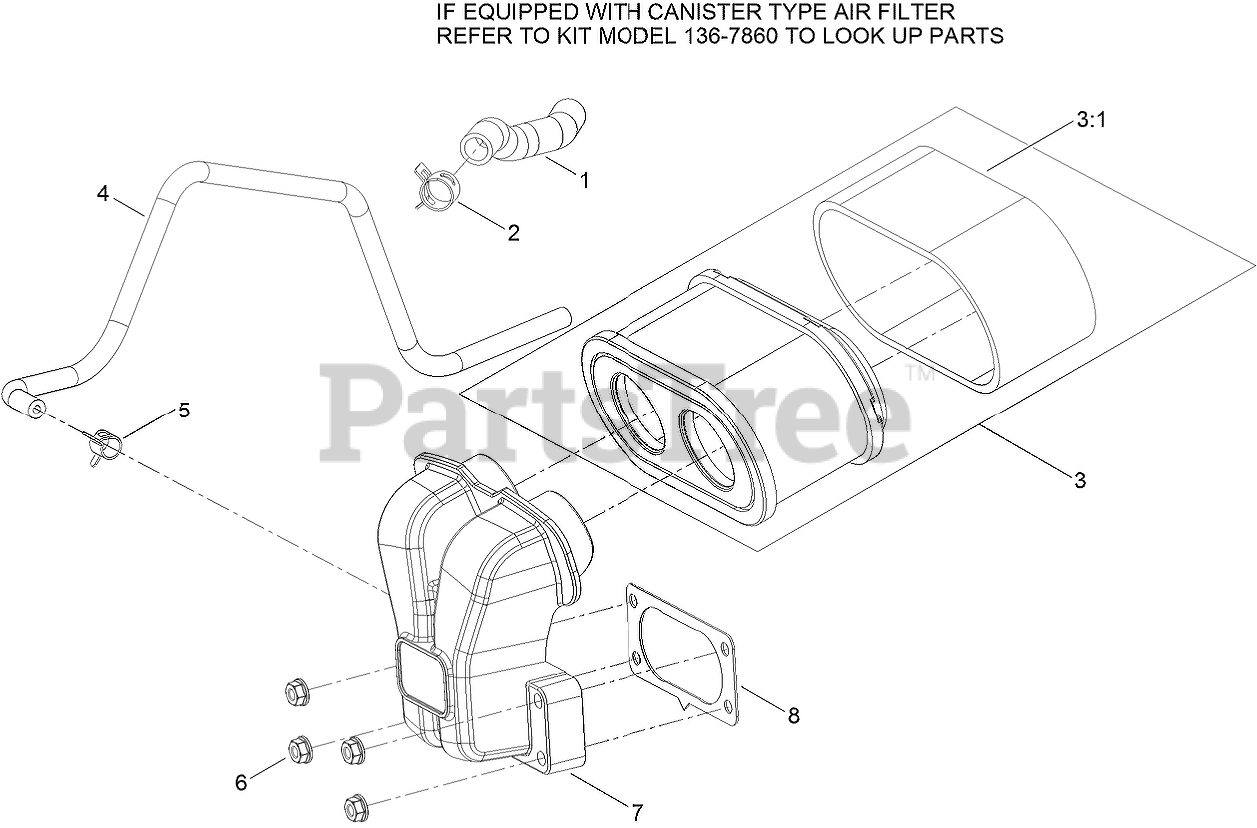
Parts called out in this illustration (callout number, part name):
1	TUBE-BREATHER
2	CLAMP-HOSE
3	AIR FILTER KIT
3:1	PREFILTER
4	HOSE-FUEL
5	CLAMP-HOSE
6	NUT-FLANGE
7	MANIFOLD-FILTER, AIR
8	GASKET-CARBURETOR
